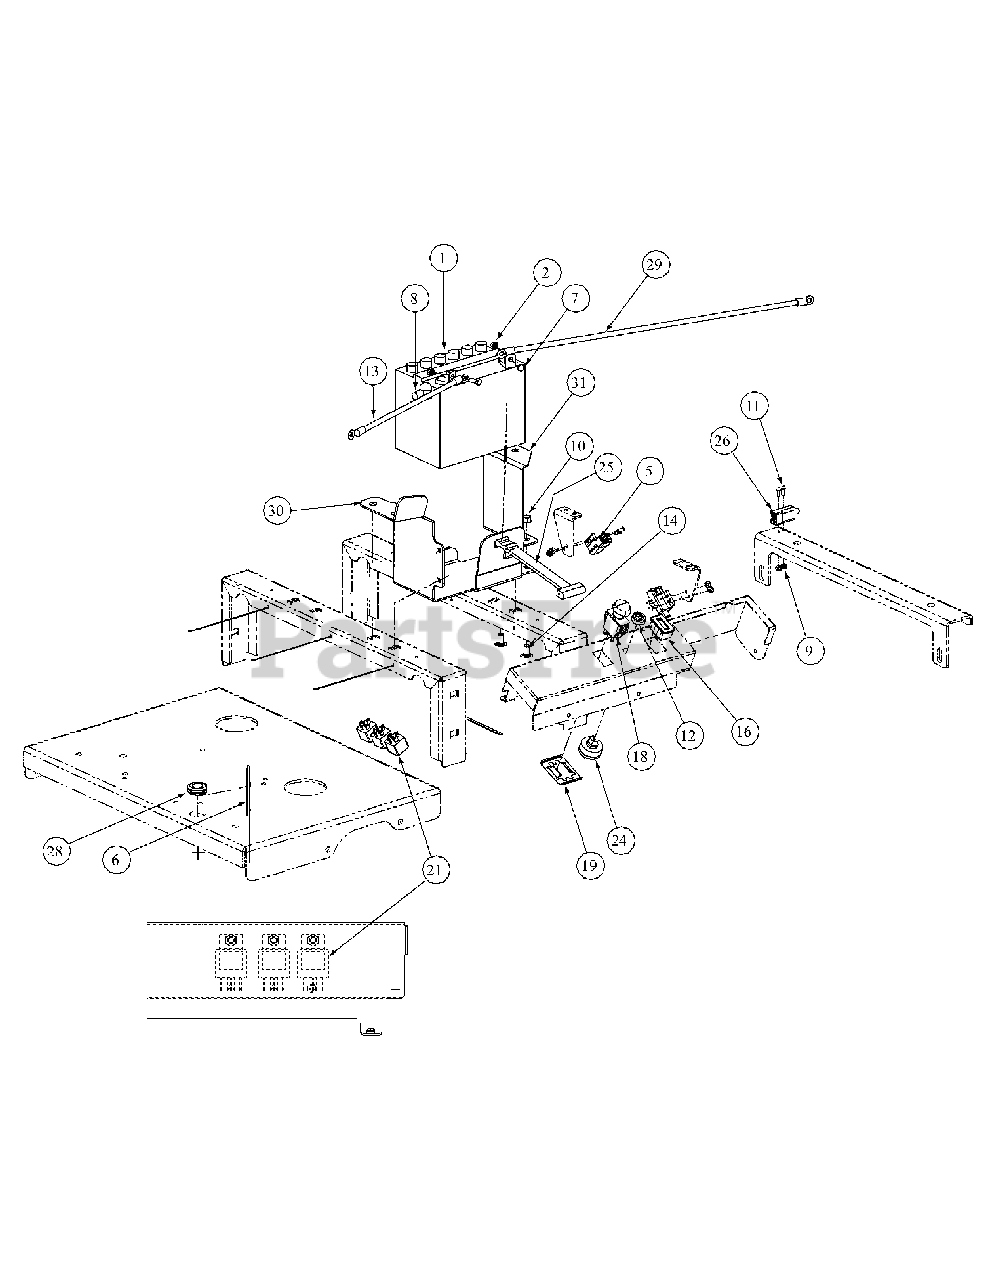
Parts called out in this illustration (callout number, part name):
1	Battery, 12V 225CCA 30 Min
2	Lock Nut, 1/4-20
5	Switch, Safety
6	Tie, Cable, 3/16 x .05 x 7.4"
7	Screw, Hex, Cap, 1/4-20 x .75
8	Boot, 1" OD Rubber Battery-PST, Red
9	Lock Nut, Nylon Insert
10	Nut, Hex, Flange Lock, 3/8-16
11	Screw, Phillips Head, Machine, 10-32 x 5/8
12	Nut, W/Cap, 5/8-32 Ignition
13	Cable, Battery, Red, 36"
14	Carriage Bolt, 3/8-16 x .75 LG.
16	Meter, Hour
18	Switch, Electric, PTO
19	Bracket, PTO Switch Retainer
21	Relay, 12V 40A
24	Switch, Ignition, 6 Pin
24	Key, Ignition
25	Strap, Battery
26	Switch, Plunger
28	Grommet, .75 ID
29	Cable, Battery Red, 28"
30	Mount Bracket, Battery
31	Mount Bracket, Battery
